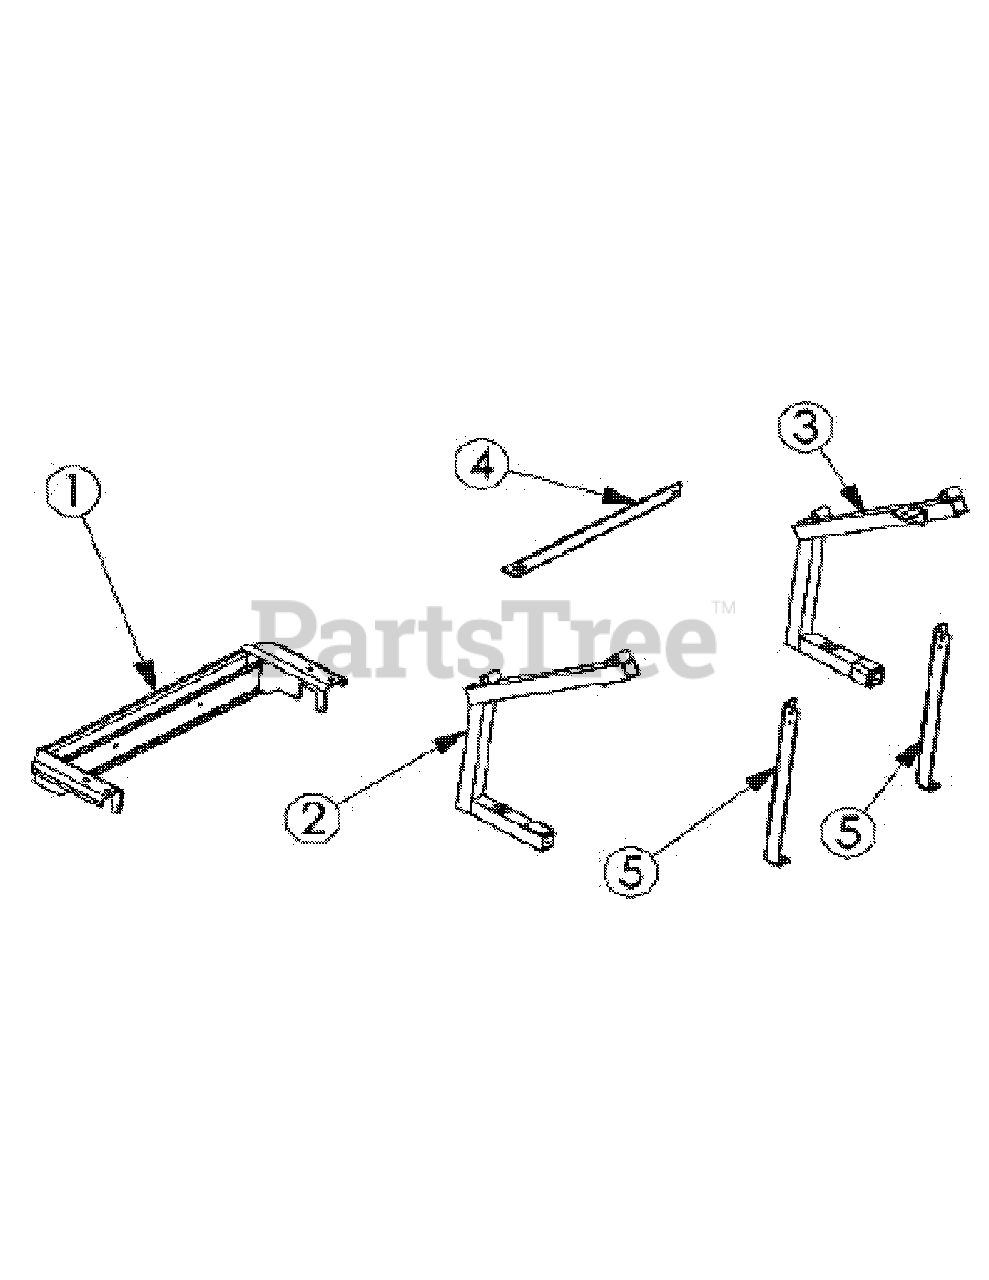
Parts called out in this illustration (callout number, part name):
1	Weight Bar
2	Catcher Mounting - MCS Right
3	Catcher Mounting - MCS Left
4	Crossbar - MCS
5	Catcher Mounting Support - MCS
